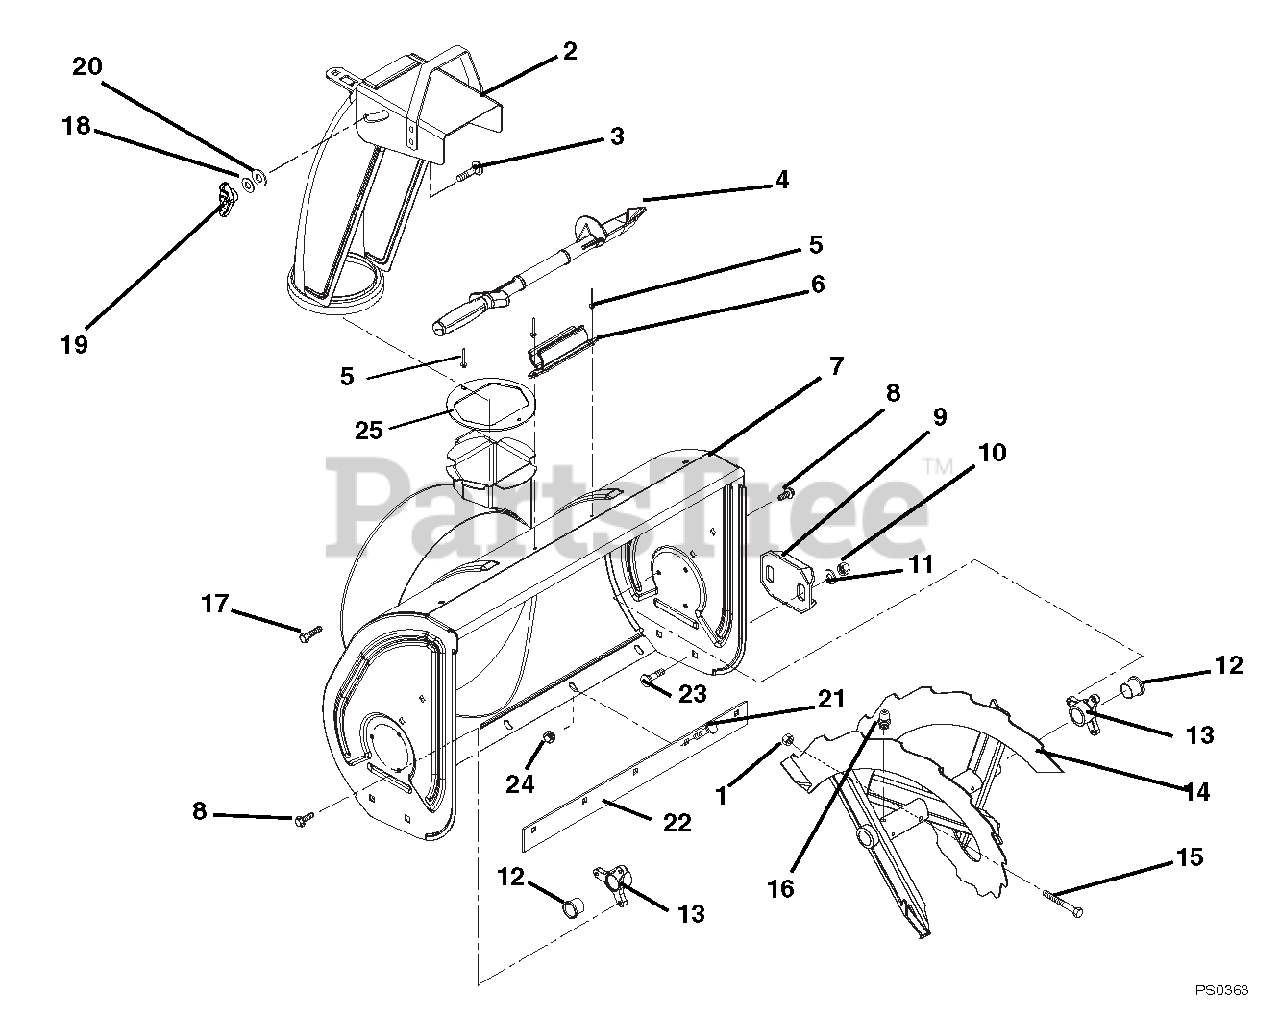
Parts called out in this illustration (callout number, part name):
1	@NUT-LK-CTR .25-20 YWZC
2	CHUTE, DISCHARGE W/CAP & DECAL
3	@BLT-RHDSSQNK .31-18X1.00 G5YZ
4	DEVICE, SNOW CLEAN OUT
5	RVT-POP .187 YZ
6	MOUNT, SNOW CLEAN OUT
7	BLOWER HOUSING - 24"
7	BLOWER HOUSING - 20"
8	SCR-TAP .25-20X.50 HWH TR YWZ
9	SKID SHOE, REVERSIBLE - ORANGE
10	@NUT-LK-CTR .38-16 YWZC
11	@WSHR-FL-STL.38X.875X.083 YWZC
12	BSHG-FLG SPLIT NYLINER .75"ID
13	BUSHING, RAKE SHAFT .75"
14	RAKE, 24" RH, BLK SERR W/ZERK
14	AUGER, 20" RH, BLK SERR W/ZERK
14	RAKE, 24" LH, BLK SERR W/ZERK
14	AUGER, LH 20", BLK SERR W/ZERK
15	SHEAR BOLT WITH NUT
16	ZERK,FITTING .25X.125 DRIVE IN
17	@SCR-TAP .31-18X.50 HWH TR YWZ
18	@WSHR-FL-STL.344X.688X.065YWZC
19	KNOB,WING .31-18 UNC NYL/TALC
20	WSHR-FL-NY .375X.75X.060
21	BLT,RDSHHDSQSHNK .31-18X.62 YZ
22	SCRAPER BLADE, 24" COMPACT HI
22	BLADE, SCRAPER - 20" COMPACT
23	@BLT-RHDSSQNK .38-16X.75 G5YZ
24	@NUT-LK-TOP-FLG .31-18 YWZC
25	BAFFLE, COMPACT DISCHARGE
